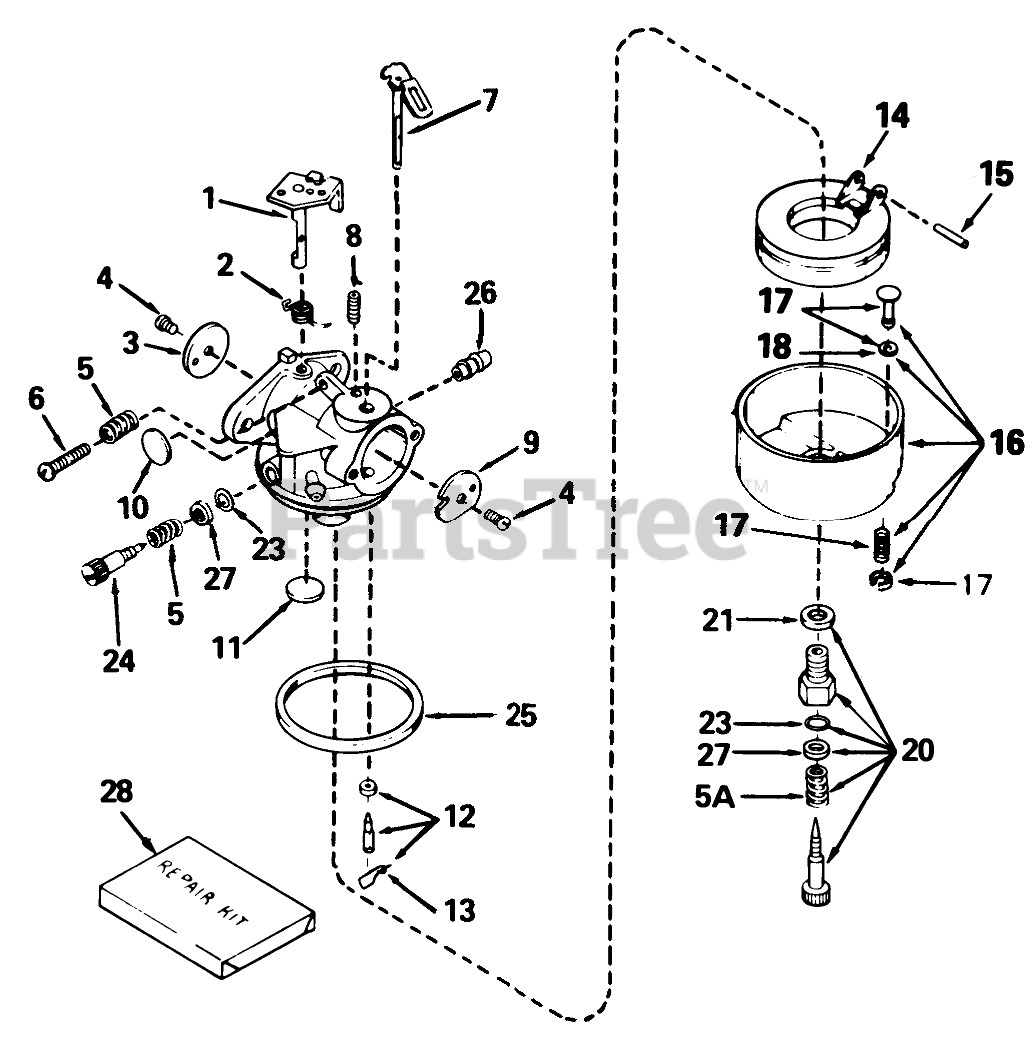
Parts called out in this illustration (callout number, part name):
1	Throttle Shaft and Lever ASM
2	Spring-Return, Throttle
3	Shutter-Throttle
4	Screw-Shutter
5	Spring-Tension
6	Screw-Throttle Crack Screw / Idle Speed
7	Choke Shaft and Lever ASM
8	Spring-Positioning, Choke
9	Shutter-Choke
10	Plug-Welch, Idle Mixture Well
11	Plug-Welch, Atmospheric Vent
12	Inlet Needle, Seat & Clip Assembly (Incl. Ref. #13)
13	Clip-Spring
14	Float
15	Shaft-Float
16	Bowl-Float (Incl. Ref. #17-18)
17	Plunger Assembly-Drain
20	Adjustment Screw Assembly (Incl. Ref. #5A, 21, 23 & 27)
21	Washer-Bowl Nut
23	"O"Ring
24	Screw-Idle Mix
25	O Ring-Bowl, Float
26	Fitting-Fuel
28	Kit-Repair
